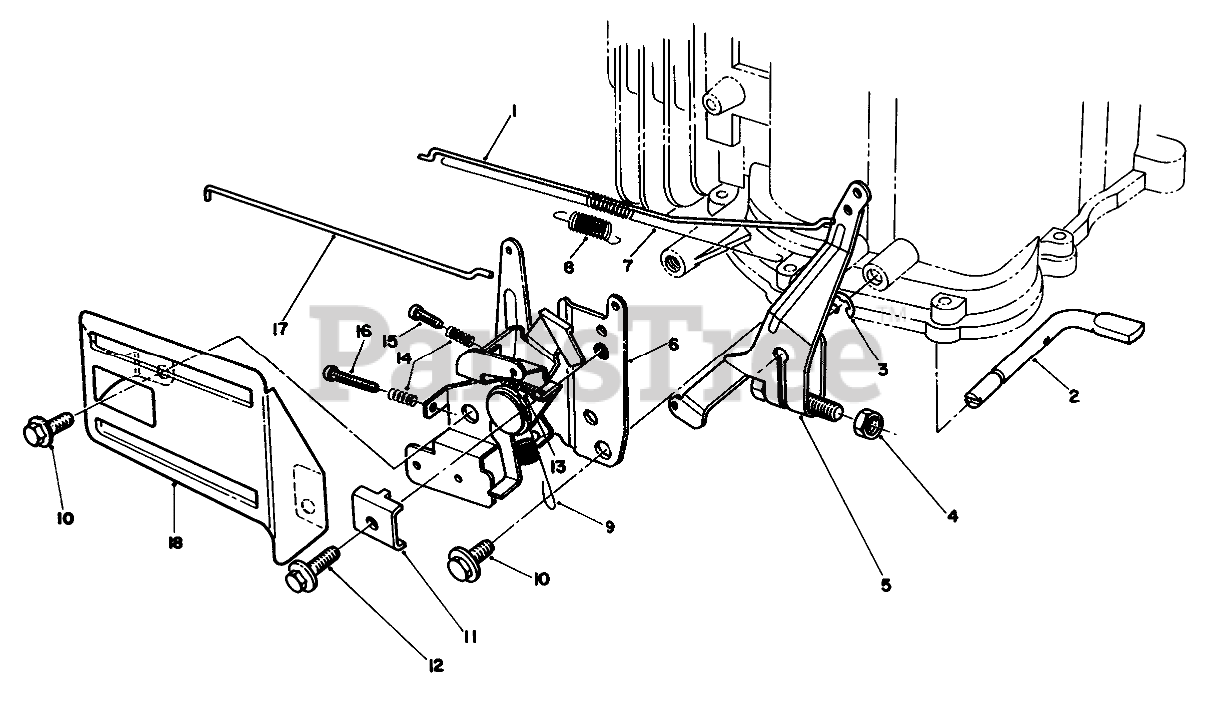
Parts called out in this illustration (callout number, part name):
1	Rod-Carburetor
2	SHAFT
3	E-RING
4	Nut
5	ARM ASM
6	THROTTLE
7	SPRING
8	SPRING
9	SPRING
11	CLAMP-CABLE
13	SPRING
14	SPRING
15	SCREW
16	SCREW
17	Rod-Choke
18	THROTTLE GUARD
